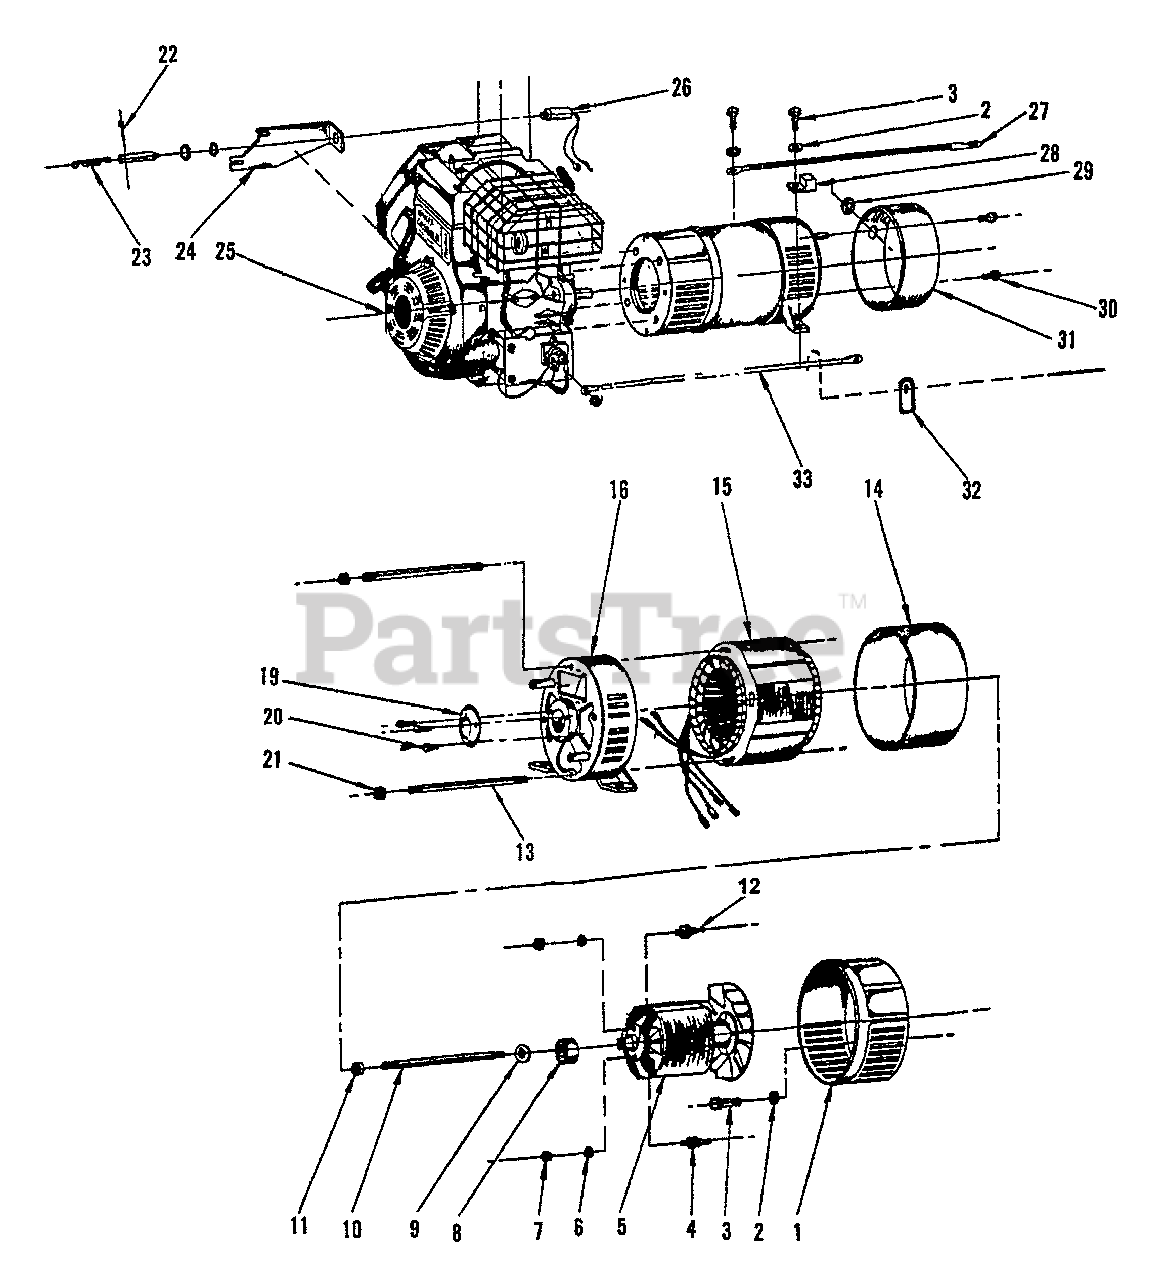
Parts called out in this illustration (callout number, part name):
1	DRIVE END ADAPTER CASTING
2	WASHER, LOCK 3×8
3	SCREW - 3/8-16×1.00" -- HEX HEAD CAP
4	DIODE
5	ROTOR ASSY
8	BEARING
9	LOCKWASHER - 5/16"
10	ROTOR THRU BOLT
11	NUT - 5/16-24 -- KEPS
12	DIODE
13	BOLT, STATOR
14	BAND, COVER
15	STATOR ASSY
16	CASTING, BEARING
19	COVER, BEARING
20	SCREW #10×24×1×2
21	NUT - 1/4-20 -- KEPS
22	PIN - COTTER
23	SPRING, ECHO-MIZER
24	BRACKET, SOLENOID
26	SOLENOID ASSY
27	CABLE, BATTERY - ( - )
28	LUG, GROUND - 1/0-14 CU/AL
29	GROMMET
30	SCREW - 10-24 -- SLOT HEAD
31	COVER, END
32	LABEL - POS. BATTERY (+)
33	CABLE, BATTERY - ( + )
